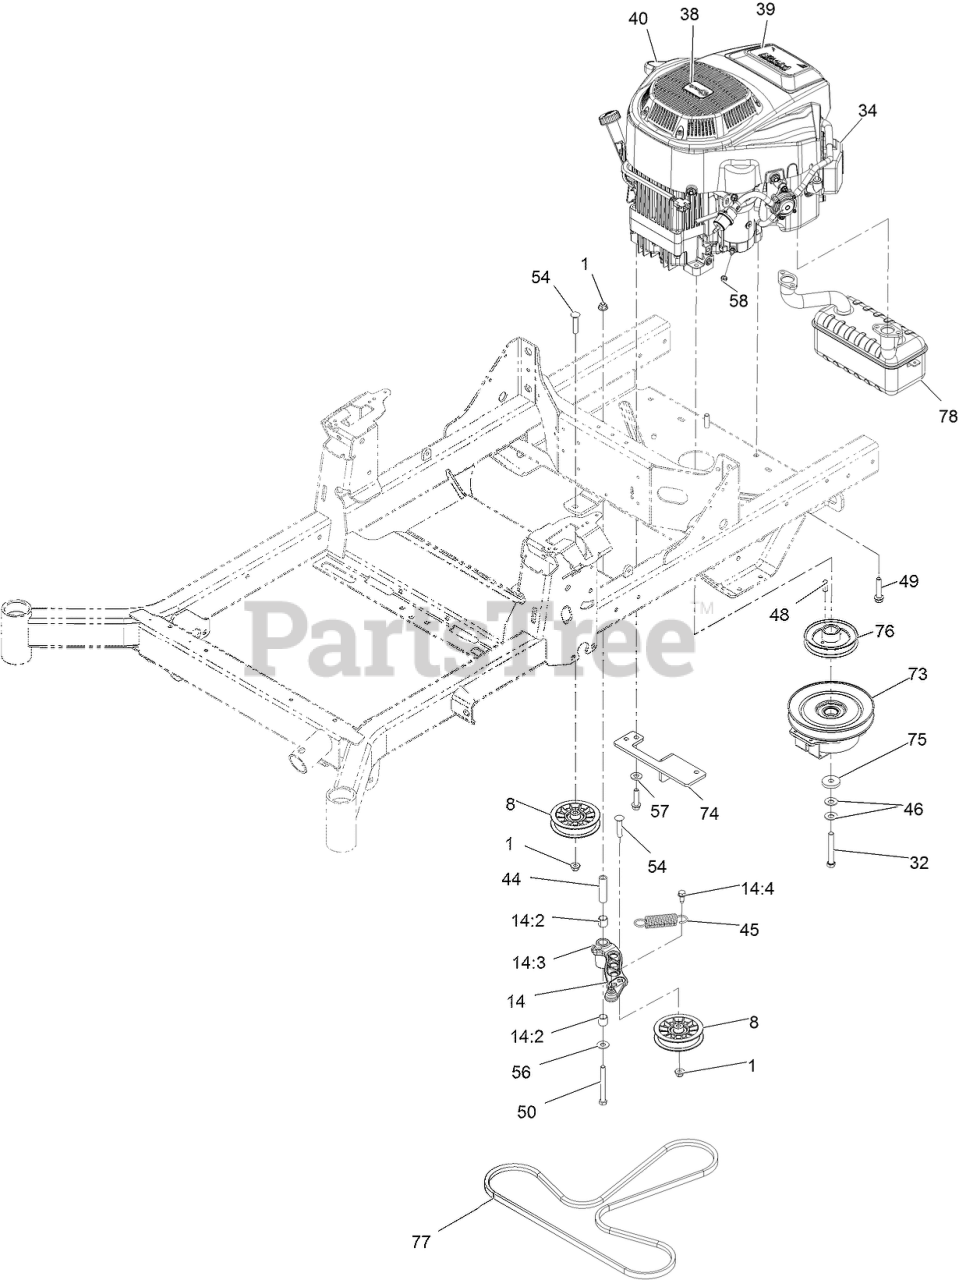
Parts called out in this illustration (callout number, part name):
1	NUT-HF, NI
8	PULLEY-FLAT IDLER
14	IDLER ARM ASM
14:2	SLEEVE-BEARING
14:3	FITTING-GREASE, 90 DEG
14:4	SCREW-THD ROLL, HWH
32	SCREW-HH W/LOCTITE
34	Engine-2P77F
39	Decal-Engine 702 V-Twin Exmark
40	DECAL-DRAIN, OIL
44	BUSHING-PIVOT, IDLER
45	SPRING-EXTENSION
46	WASHER-SPRING
49	SCREW-HWH
50	SCREW-HH
54	SCREW-CARR
56	WASHER-FLAT
57	WASHER-BELLEVILLE
73	Clutch 1.00
74	Anchor Clutch [black]
75	WASHER-CLUTCH
76	Sheave-Engine
77	V-BELT
78	MUFFLER
